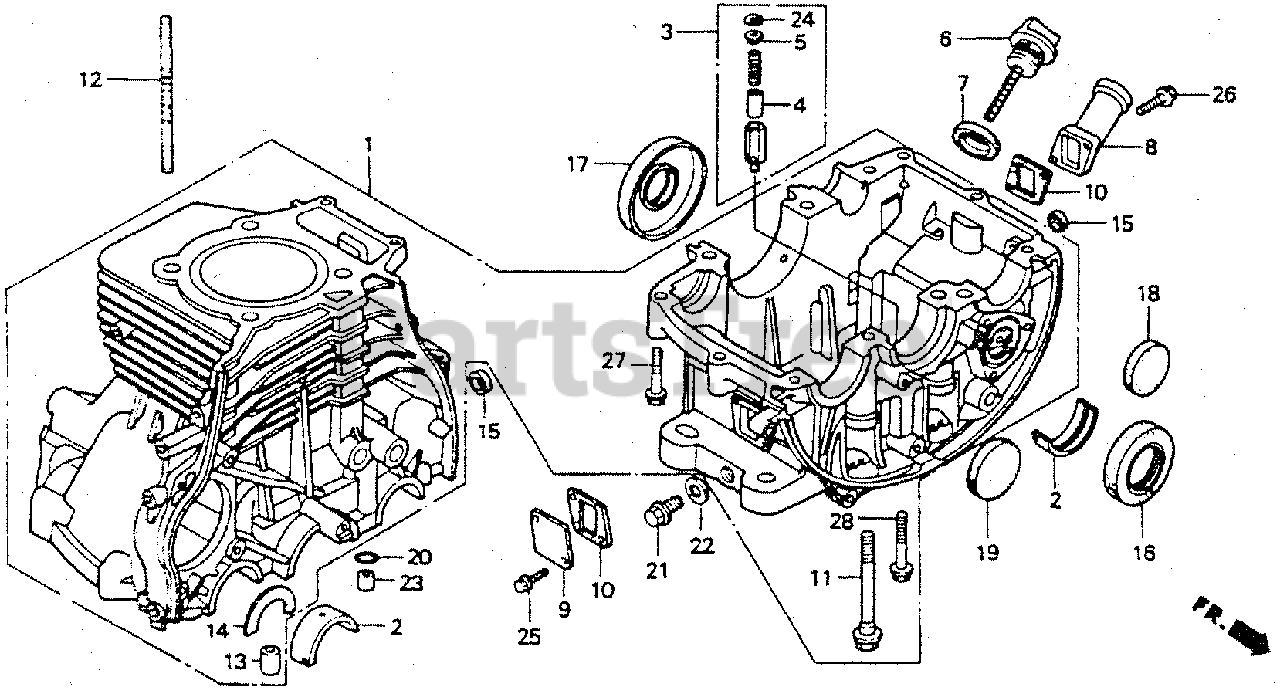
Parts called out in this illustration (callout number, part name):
1	CYLINDER ASSY. (P-TYPE)
2	BEARING A, MAIN (BLUE)
2	BEARING B, MAIN (BLACK)
2	BEARING C, MAIN (BROWN)
2	BEARING D, MAIN (GREEN)
2	BEARING E, MAIN (YELLOW)
2	BEARING F, MAIN (PINK)
2	BEARING G, MAIN (RED)
2	BEARING A, MAIN (US 0.25) (BLACK)
2	BEARING B, MAIN (US 0.25) (BROWN)
2	BEARING C, MAIN (US 0.25) (GREEN)
2	BEARING A, MAIN (US 0.75) (BLACK)
2	BEARING B, MAIN (US 0.75) (BROWN)
2	BEARING C, MAIN (US 0.75) (GREEN)
3	VALVE ASSY., RELIEF (NOT AVAILABLE)
4	VALVE, RELIEF
5	SEAT, RELIEF VALVE
6	CAP, OIL FILLER
7	GASKET, OIL FILLER CAP
8	EXTENSION, OIL FILLER
9	PLATE, EXTENSION
10	GASKET, EXTENSION OIL FILLER (NON-ASBESTOS)
11	BOLT-WASHER (11X115)
12	BOLT, STUD (10X103.5)
13	PIN, DOWEL (13X20)
14	SET-RING (90)
15	OIL SEAL (8X14X5)
16	OIL SEAL (40X67X10)
17	OIL SEAL (36X90X9)
18	PLUG, SEAL (47MM)
19	PLUG, SEALING (52MM)
20	O-RING (9.8X1.9)
21	BOLT, DRAIN PLUG (14MM)
22	WASHER, DRAIN PLUG (14MM)
23	PIN A, DOWEL (10X16)
24	CIRCLIP (INNER) (12MM)
25	BOLT, FLANGE (6X16)
26	BOLT, FLANGE (6X22)
27	BOLT, FLANGE (8X40)
28	BOLT, FLANGE (8X50)
